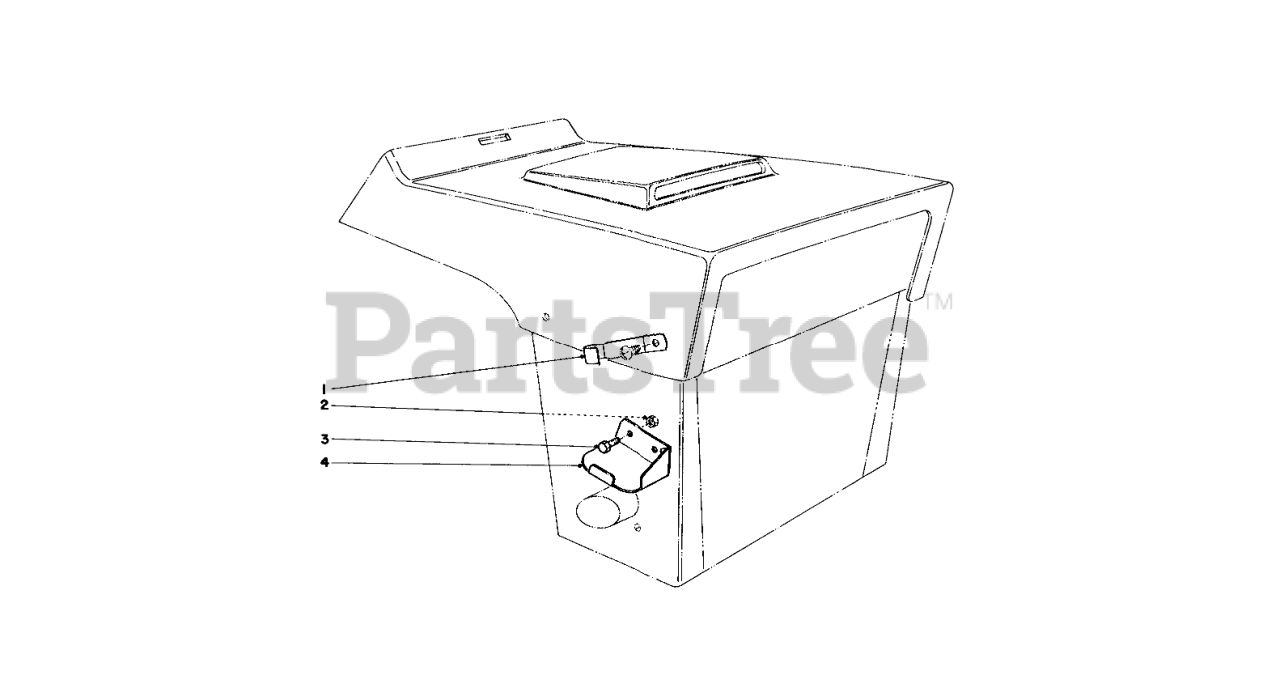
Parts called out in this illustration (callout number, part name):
1	Bracket Trimmer
2	Nut
3	SCREW-HH
4	Trimmer Support
